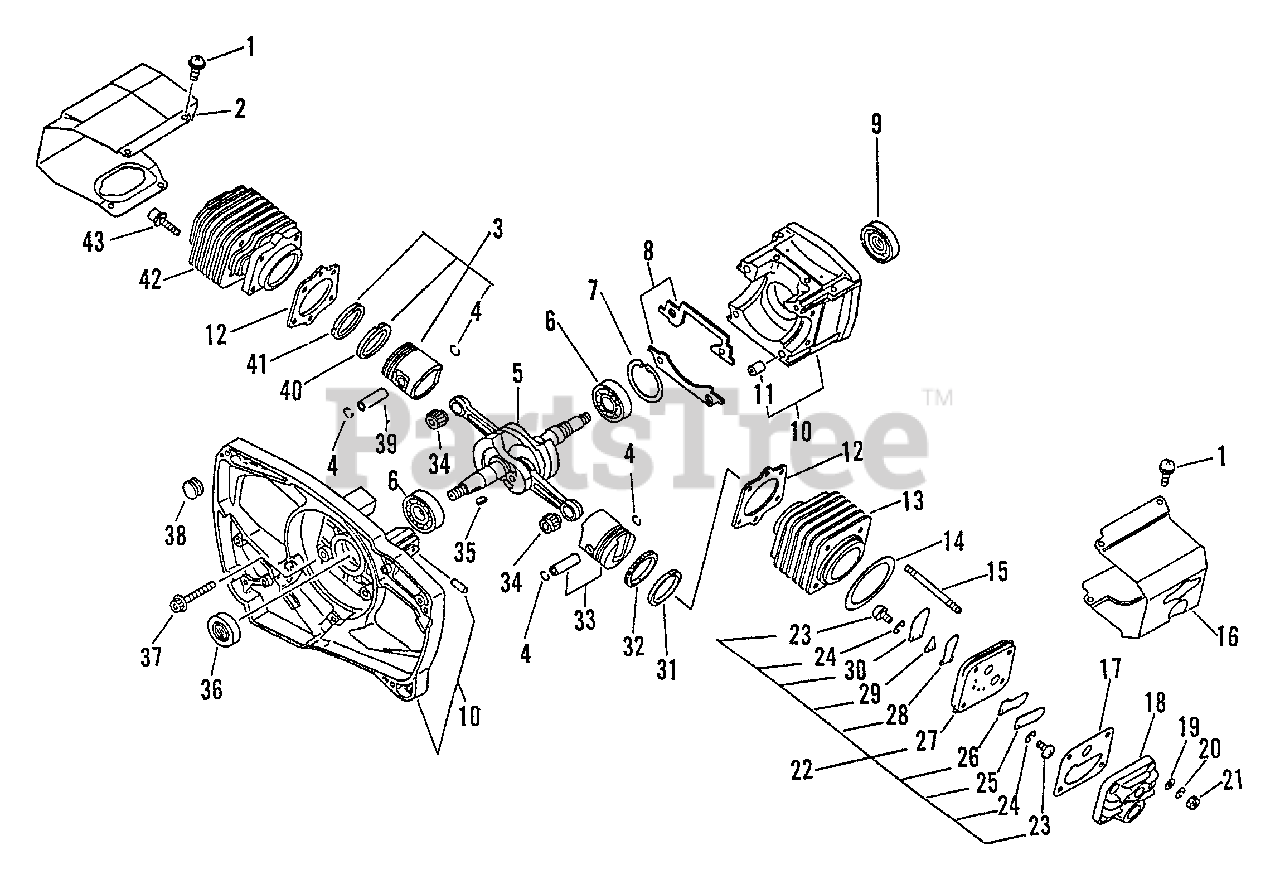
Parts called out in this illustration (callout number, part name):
1	SCREW - 4X10
2	COVER, ENGINE
3	PISTON KIT
4	RING, RETAINING
5	CRANKSHAFT ASSY
6	BEARING, BALL - 6202
7	RING, RETAINING - 35
8	GASKET, CRANKCASE
9	SEAL, OIL
10	CRANKCASE KIT
11	PIN - LOCATING
12	GASKET, CYLINDER
13	CYLINDER
14	PACKING
15	STUD
16	SHIELD, CYLINDER
17	GASKET, CYLINDER
18	HEAD, CYLINDER
19	WASHER - 5
20	LOCKWASHER - 5
22	REED VALVE SET
23	SCREW - 3X8
24	LOCKWASHER - 3
25	GUIDE, VALVE
26	VALVE, REED
27	FIXTURE, REED VALVE
28	VALVE, REED
29	VALVE, REED
30	GUIDE, VALVE
31	RING, PISTON
32	RING, OIL
33	PISTON ASSY
34	BEARING, NEEDLE
36	SEAL, OIL
37	SCREW - 5X35
39	PIN, PISTON
40	RING, PISTON
41	RING, PISTON
42	CYLINDER
43	SCREW - 5X20
